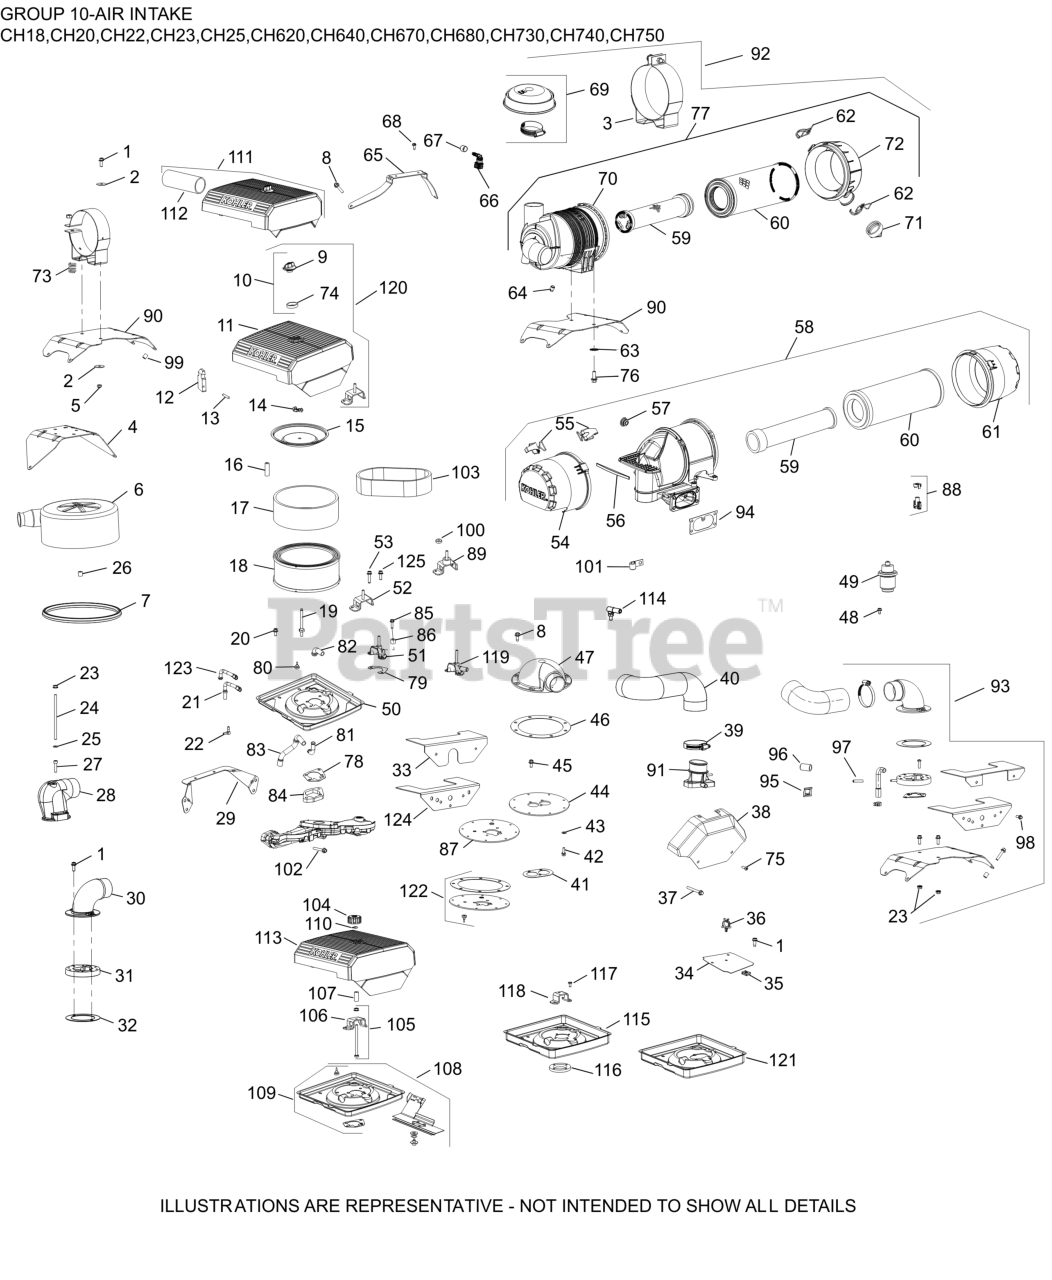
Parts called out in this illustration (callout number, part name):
9	KNOB, COVER
10	KIT, KNOB W/SEAL
11	COVER, AIR CLEANER
14	NUT, WING
15	COVER, INNER AIR CLEANER
16	SEAL BREATHER
17	PRE-CLEANER (HIGH)
18	AIR FILTER ELEMENT
20	SCREW, FLG THD FRM M6X1.0X16
21	HOSE, EVAP
22	CONNECTOR, EVAPORATIVE HOSE
29	AIR CLEANER BRACKET
48	SCREW, THREAD FORMING
50	KIT, AIR CLEANER BASE
52	BRACKET, AIR CLEANER
78	GASKET, AIR CLEANER BASE
102	SCREW, FLG M6X1.0X40
120	KIT, AIR CLEANER COVER
